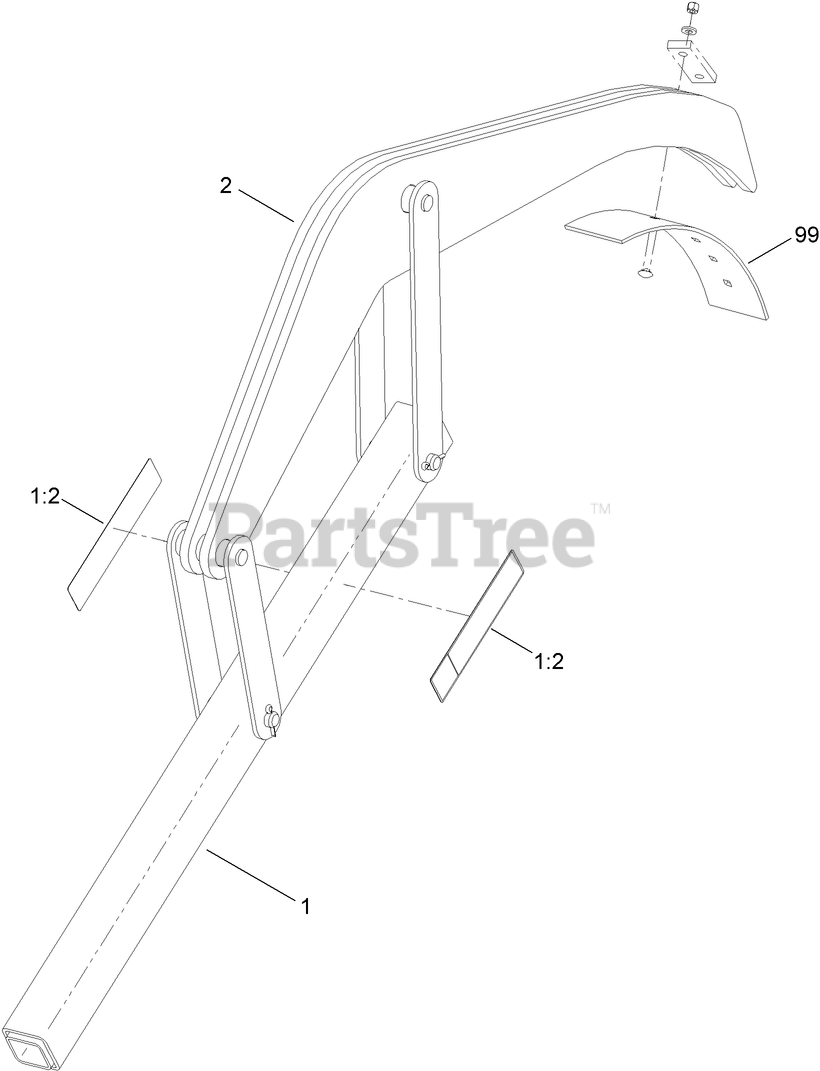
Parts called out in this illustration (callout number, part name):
1	CRUMBER TUBE ASM
1:2	DECAL-DANGER, ENTANGLEMENT
2	I / BASIC CRUMBER ASM
99	BLADE-MANUAL CRUMBER, 6 INCH CUT
99	BLADE-MANUAL CRUMBER, 8 INCH CUT
